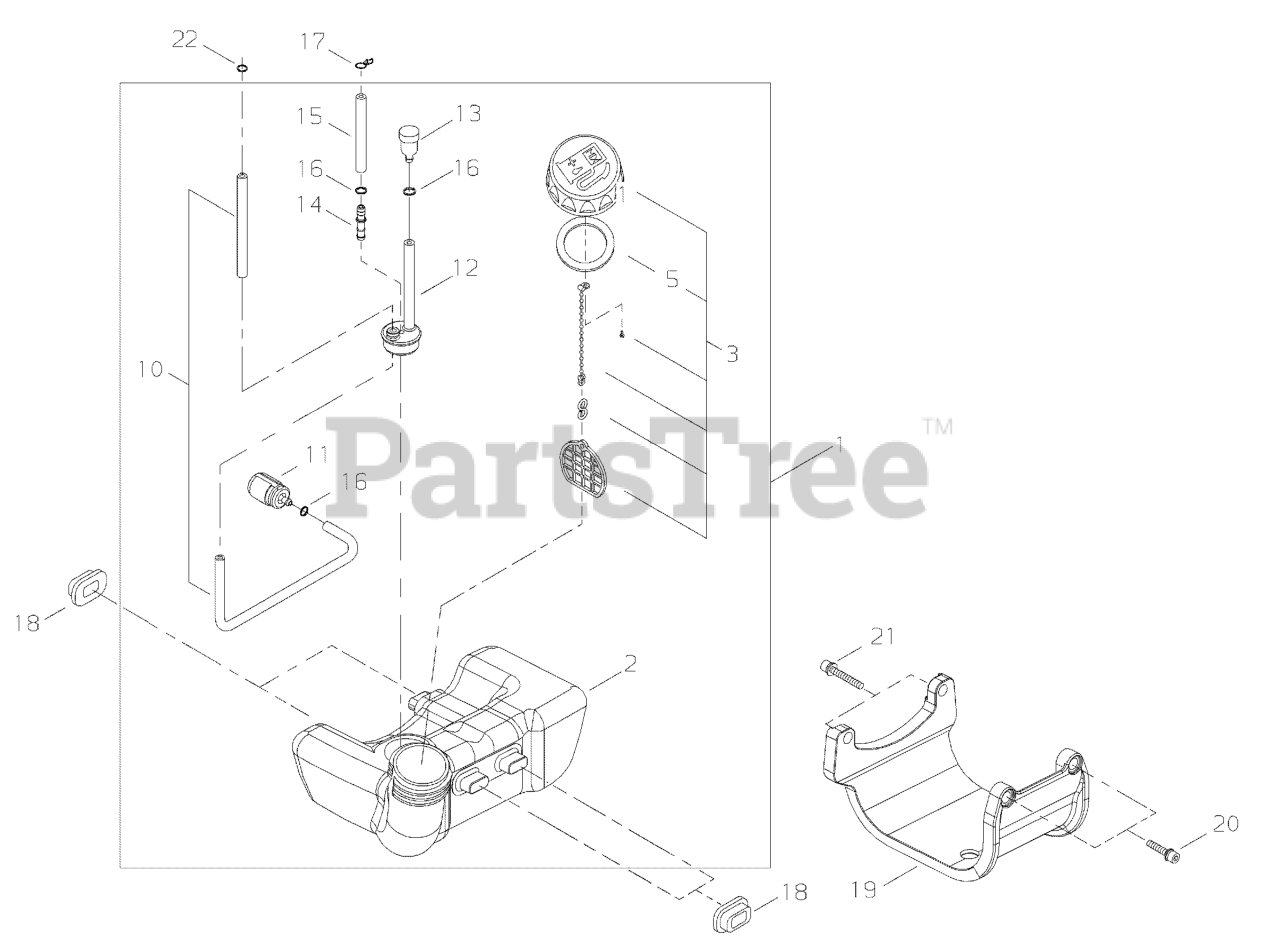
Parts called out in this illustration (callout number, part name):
1	FUEL TANK ASSY
2	TANK, FUEL
3	CAP ASSY
5	GASKET, CAP
10	PIPE - FUEL
11	FILTER, FUEL
12	PIPE ASSY
13	VENT, FUEL TANK
14	CONNECTOR, PIPE
15	PIPE - RETURN
16	RING, RETAINING - 6
17	CLIP - SPRING
18	CUSHION, FUEL TANK
19	GUARD, FUEL TANK
20	SCREW - 5X18
21	SCREW - 5X40
22	RING, RETAINING - 6
